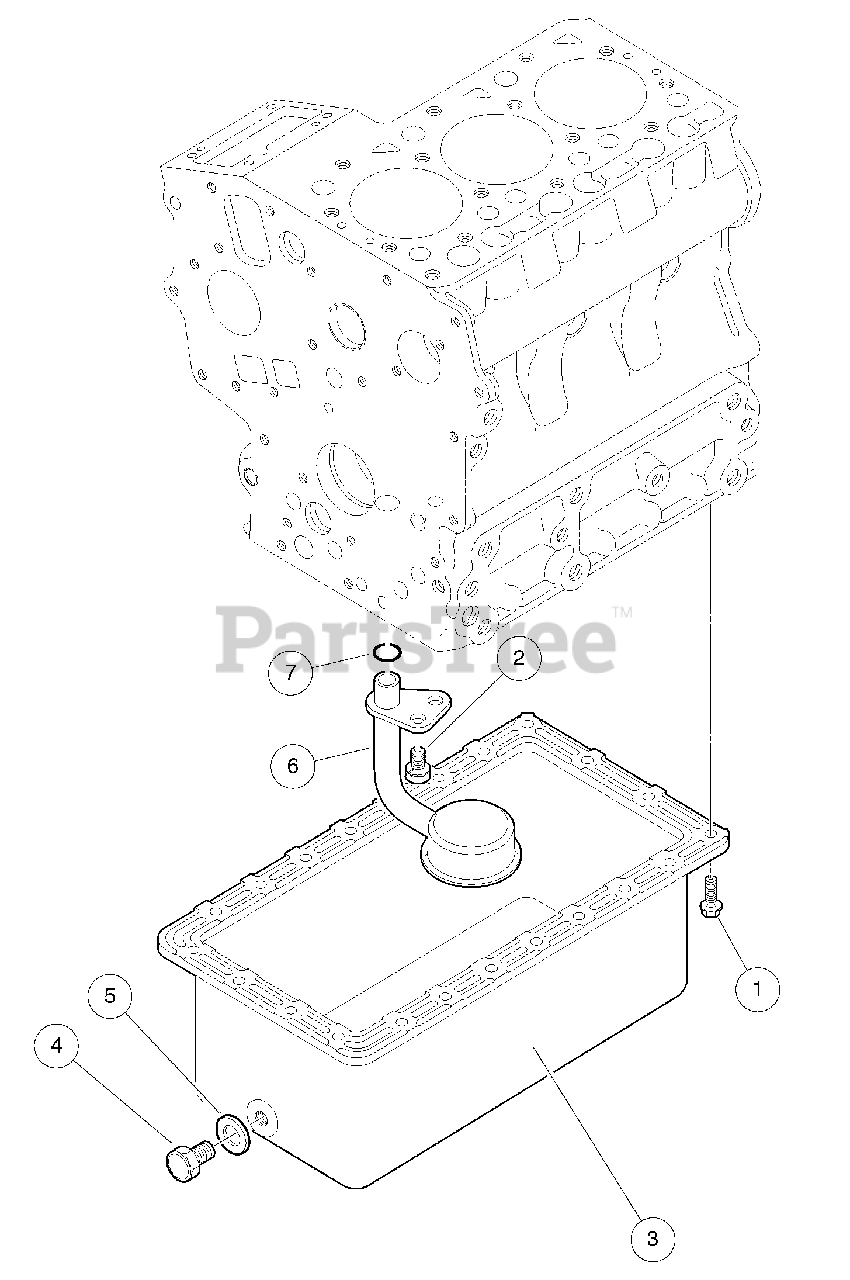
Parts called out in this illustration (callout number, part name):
1	Bolt, M6 X 1 X 14
2	Bolt, M8 X 1.25 X 15
4	Plug, Drain, M12 X 14
5	Gasket, 20 X 13
6	Filter, Oil, Pick Up
7	O Ring, 20 X 17
